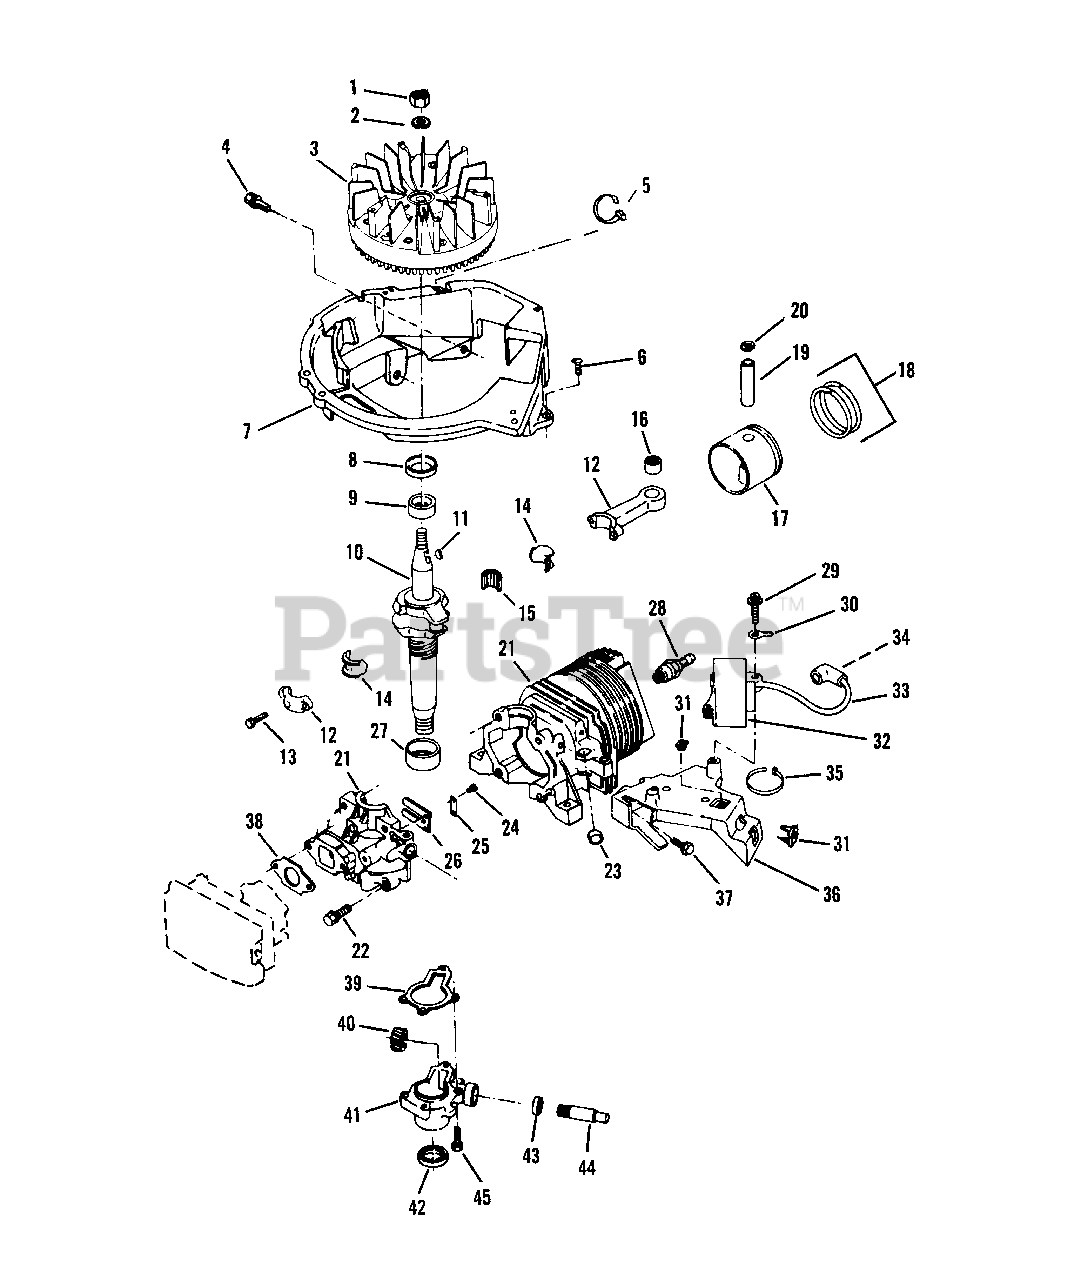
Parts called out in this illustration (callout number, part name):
1	Nut-Flywheel
2	Lockwasher
3	Flywheel
4	Screw
5	Tie Strap
6	Screw-Shd. Base to C.D. Brkt.
7	Base-Shroud
8	Oil Seal-Upper
9	Bearing-Upper
10	Crankshaft
11	Key-Flywheel
12	Connecting Rod Assembly
13	Screw-Cap
14	Liner Split
15	Needle Bearing Set
16	Bearing Assembly
17	Piston and Ring Set
18	Ring Set
19	Wrist Pin
20	Retaining Ring
21	Cylinder & Crak'c Cover Assembly
22	Screw-Cover to Crankcase
23	Plug
24	Screw-Reed to Crankcase Cover
25	Plate-Reed Hold Down
26	Reed
27	Bearing-Lower
28	Spark Plug
29	Screw-C.D. Mounting
30	Terminal-Ground Lead
31	Grommet-C.D. Bracket
32	C.D. Ignition Module & Lead Asy.
33	High Tension Lead & Cvr. Asy.
34	Spring Terminal
35	Tie Strap
36	Bracket-Ignition Mounting
37	Screw
38	Gasket-Carb. to Crankcase Cover
39	Gasket-Gear Box
40	Gear
41	Gear Box Assembly
42	Oil Seal Crankshaft
43	Seal-Driveshaft
44	Driveshaft
45	Screw-Gear Box
